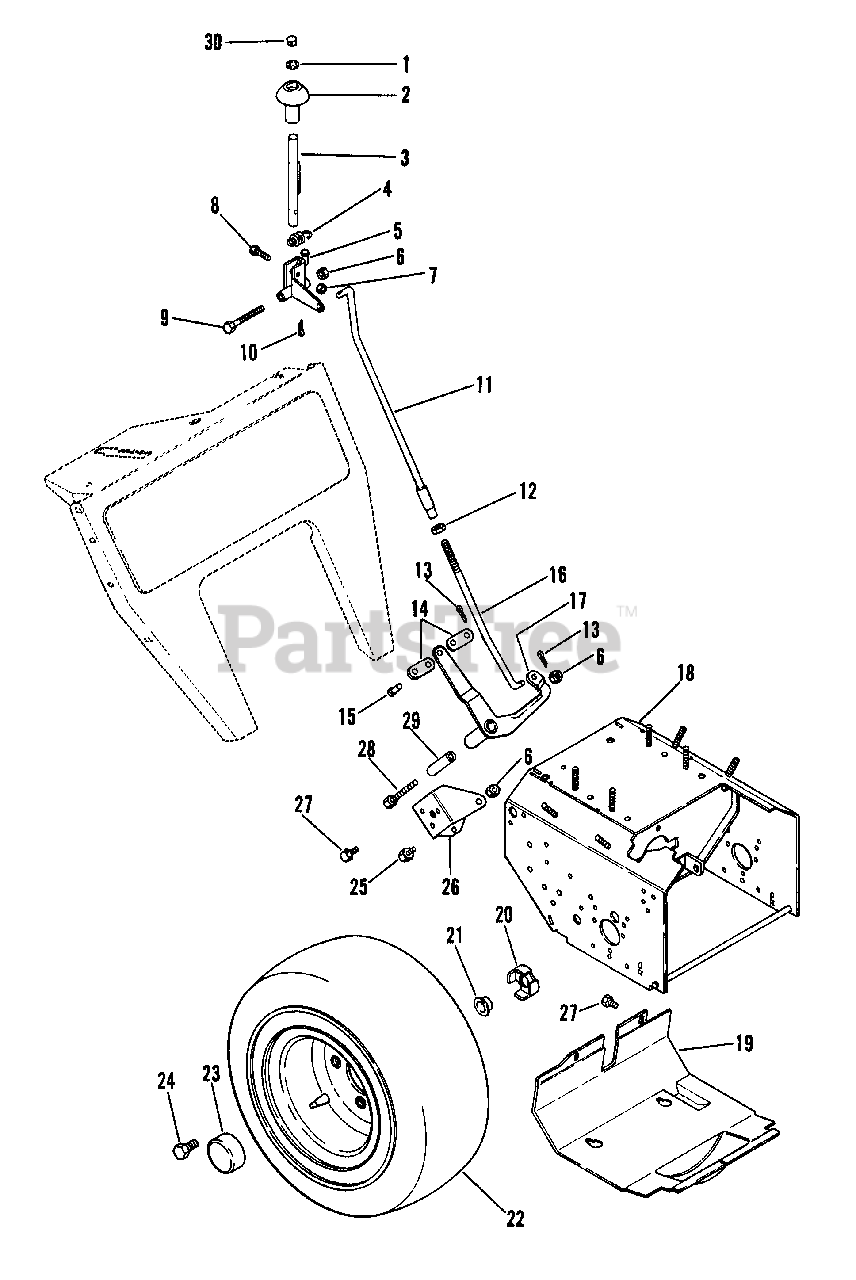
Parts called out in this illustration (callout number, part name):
1	RG-RTNG-EXT .500X.015
3	ROD
4	SG-TENS .055X.33X1.31 WLD 7
6	NUT-LK .312-18 GR A PL
7	NUT-LK-CTR .250-20 PL
8	BLT-HEX .25-20X1.00 GR2
9	BLT-HEX .31-18X2.50 PL GR2
10	PIN-COTR .12X.75 PL
11	UPPER SHIFT ROD
12	NUT-HEX .312-24 PL
13	PIN-COTR .09X.75 PL
14	SHIFT LINK
15	CLEVIS PIN
16	LOWER SHIFT ROD
17	LEVER - SHIFT ARM
18	TRACTOR FRAME ST824-ST1032
19	BOTTOM COVER
20	SPINDLE CUP
21	PUSHNUT
22	TUBE
23	HUB CAP
24	SCR-TAP .500-20X.62 HH PL
25	BLT-HEX .31-18X.50 PL GR2
26	BRACKET SHIFT LEVER
27	SCR-TAP .312-18X.50 HWH PL TR
28	BLT-HEX .31-18X3.00 PL GR2
29	SPACER .5 X .33 X 2.4
30	HOLE PLUG
